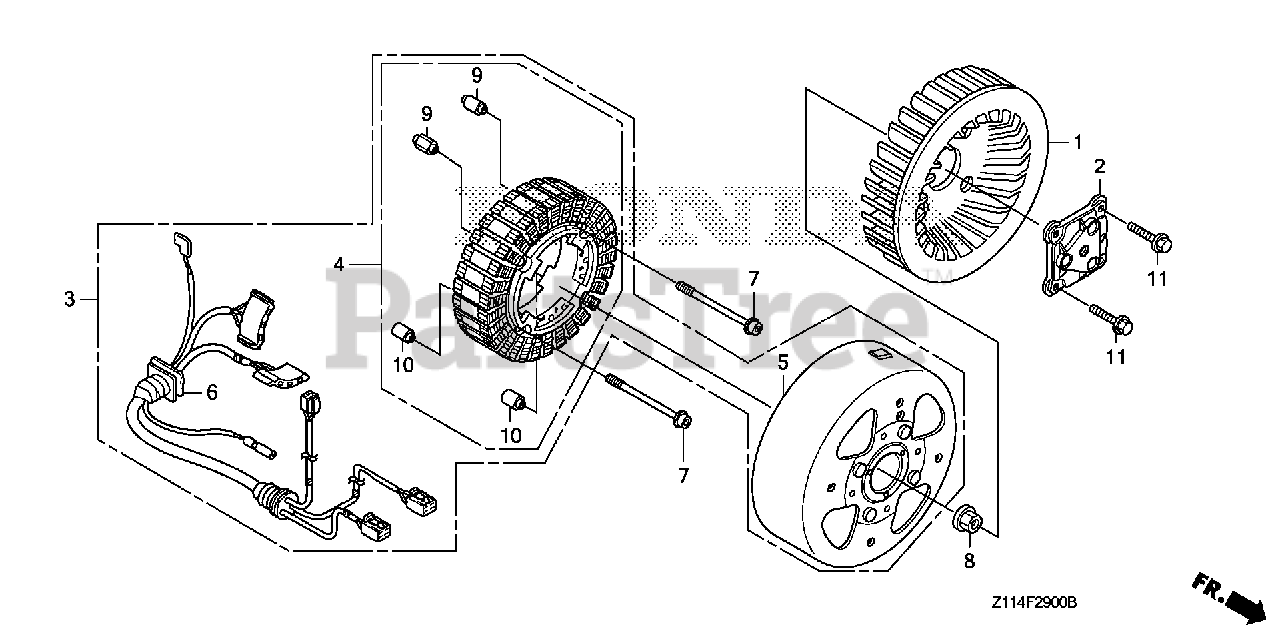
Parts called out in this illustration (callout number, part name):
1	FAN, COOLING
2	ADAPTER, RECOIL PULLEY
3	GENERATOR ASSY.
4	CORE SET, STATOR COIL
6	WIRE HARNESS ASSY., GENERATOR
7	BOLT, FLANGE SOCKET (6X74) (CT200)
8	NUT, SPECIAL (16MM)
9	COLLAR, STATOR (6.3X13X25.5)
10	COLLAR, STATOR (6.3X13X20.5)
11	BOLT, FLANGE (6X25)
